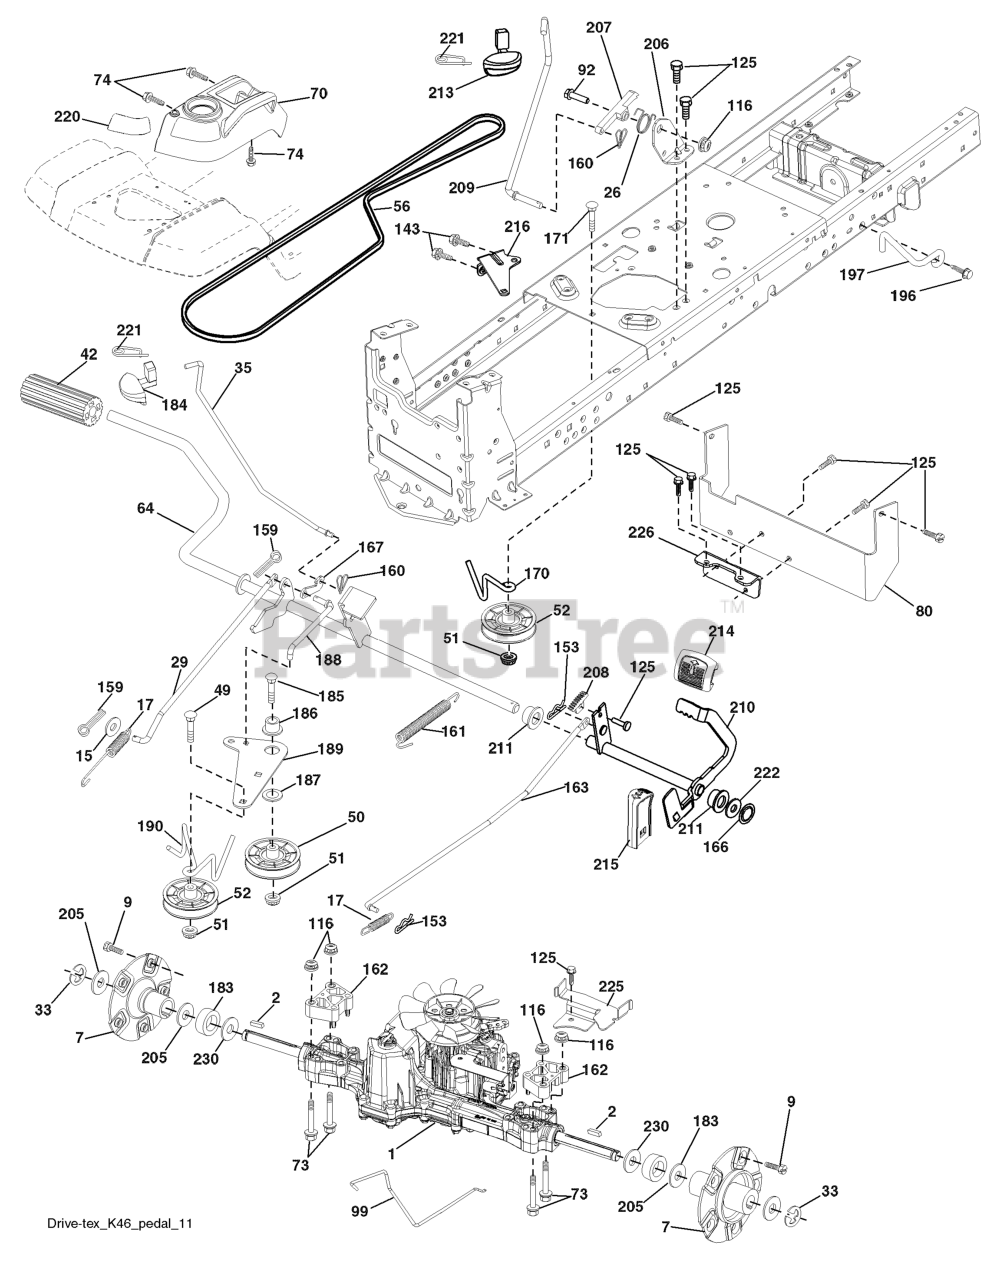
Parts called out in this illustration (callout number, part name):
1	TRANSAXLE.K46BN.PEDAL CONTROL
2	KEY.SQUARE.187X2.500
7	HUB.ASM.WHEEL.REAR.22"
9	HUB BOLT
15	WASHER
17	SPRING.BRAKE.K46.GREEN
26	SPRING.RETURN.CRUISE
29	ROD.BRAKE.K46
35	ROD.BRAKE.PARKING.GT.H
42	PEDAL COVER T
49	BOLT
50	IDLER.FLAT.910.OFFSET
51	NUT LOCK FLG 3/8-16 UNC
52	IDLER.V-GROOVE.910.OFFSET
56	V-BELT.MOWER.92.40.42/K46
64	SHAFT.ASM.PEDAL.BRK.CNTR
70	RP CONSOLE.ASM.PCH.W/TB
73	BOLT.HEX.FLNG.5/16-18X3.75
74	SCREW.HI-LO.CONSOLE
80	STRAP TORQUE
92	BOLT
99	ROD.SPRING.BYPASS.K46.TEX.GT
116	NUT LOCK HEX FLANGE 5/16-18
125	SCREW
143	Screw Thdrol 5/16-18 x 1/2
153	RETAINER M
159	COTTER PIN
160	RETAINER CLIP
161	SPRING, RETURN LT
162	SPACER.TRANSAXLE.18&22
163	ROD.CONTROL.PEDAL.K46
166	NUT.PUSH.625.2006
167	LATCH.BRAKE.SPRING
170	KEEPER.V-IDLER.CENTER.
171	BOLT
183	SPACER.SPLIT.800X.350
184	HANDLE.PARKG.BRK.HUSQ X667
185	BOLT
186	SPACER.RETAINER
187	WASHER 12/32X2X10GA
188	RP.LINK.CLUTCH.GROUND.DRIVE
189	BELLCRANK.GROUND.DRIVE.TEX.
190	KEEPER.BELLCRANK.DRIVE
196	SCREW 3/8-16X1
197	BRKT.ANIT-ROTATION.CLUTCH
206	BRKT.MOUNT.LATCH.CRUIS
207	LATCH.CONTROL.CRUISE
208	GEAR.SECTOR.CONTROL.CR
209	ROD.CONTROL.CRUISE.GT.
210	ROCKER.ASM.PEDAL.CONTR
211	BEARING.NYLON
213	KNOB.CONTROL.CRUSIE.HU
214	PEDAL.FORWARD.TEX.GT.4
215	PEDAL.REVERSE.TEX.GT.4
216	BRACKET.PULLEY.IDLER.W/TEX
220	REFLECTOR.RH.TEX GT
221	RETAINER.SPRING.CLIP.H
222	WASHER
225	KEEPER.BELT.TRANSAXLE.K46
226	BRKT.MOUNT.TORQUE.K46.
230	WASHER.HARDENED
231	IDLER.V-GROOVE.1.688.OFFSET
